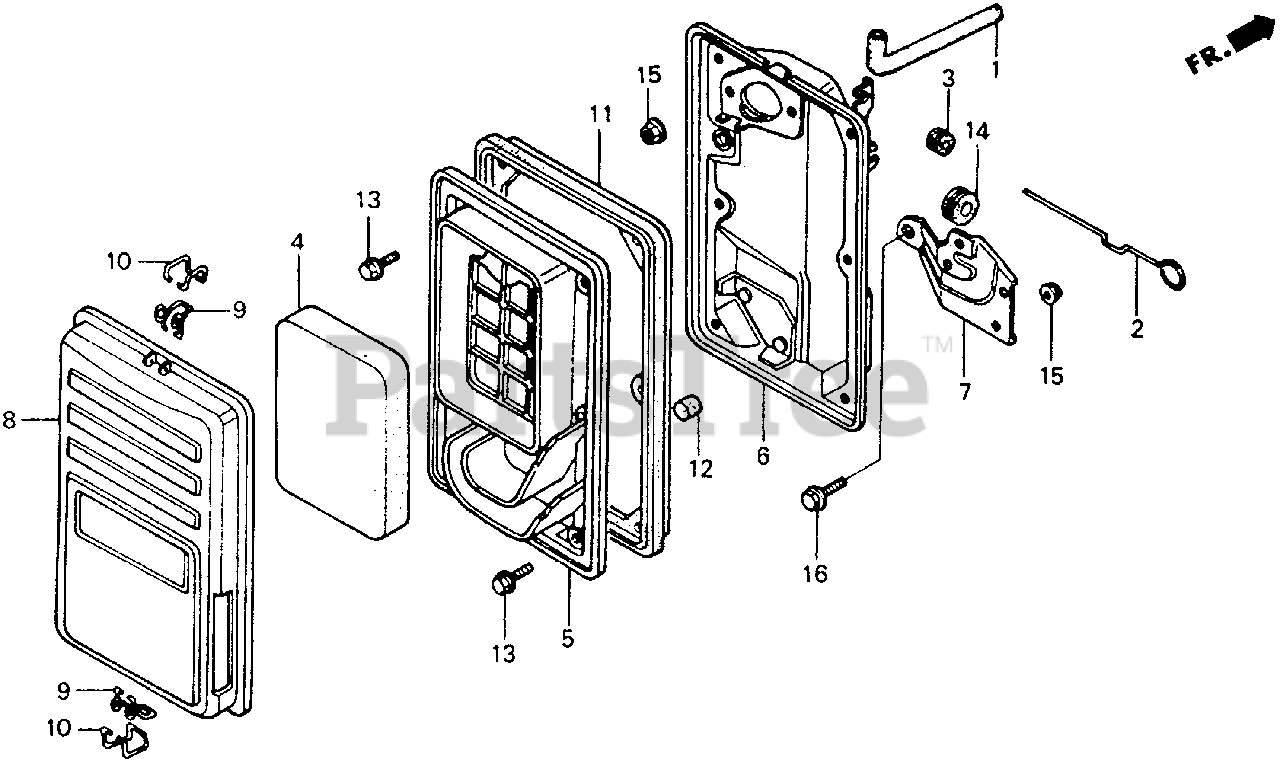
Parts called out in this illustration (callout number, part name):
1	TUBE, BREATHER
2	ROD, CHOKE CONTROL
3	GROMMET, CHOKE ROD
4	ELEMENT, AIR CLEANER
5	SEPARATOR, AIR CLEANER
6	HOUSING, AIR CLEANER (NOT AVAILABLE)
7	STAY, AIR CLEANER
8	COVER, AIR CLEANER
9	CLIP A, AIR CLEANER WIRE
10	CLIP B, AIR CLEANER WIRE
11	SEAL, AIR CLEANER
12	FILTER, DRAIN TUBE
13	BOLT, SETTING
14	RUBBER, CONTROL BOX
15	NUT, FLANGE (6MM)
16	BOLT, FLANGE (8X16)
